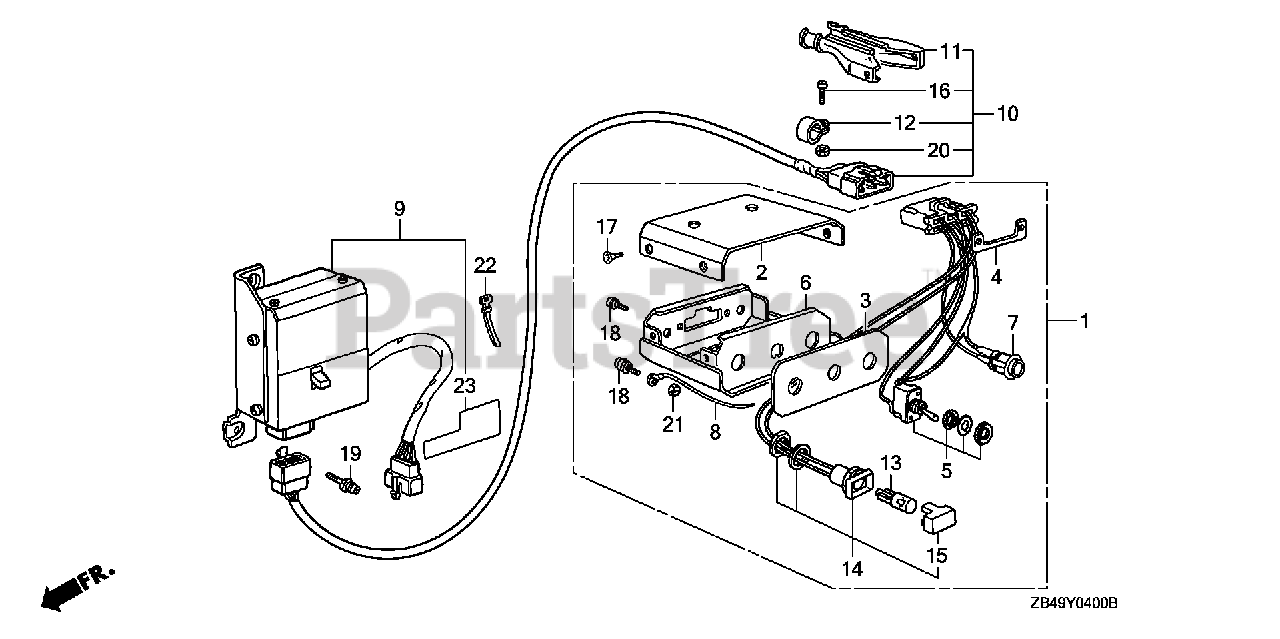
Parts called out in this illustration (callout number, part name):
1	BOX ASSY., SWITCH *R280* (POWER RED)
2	COVER (UPPER) *R8* (BRIGHT RED)
2	COVER (UPPER) *R280* (POWER RED)
3	PLATE, SWITCH & INDICATOR
4	PLATE, CONNECTOR SETTING
5	SWITCH, TOGGLE
6	CASE, SWITCH *R8* (BRIGHT RED)
6	CASE, SWITCH *R280* (POWER RED)
7	SWITCH, PUSH
8	WIRE, GROUND
9	BOX ASSY., RELAY
10	CABLE, REMOTE CONTROL (10M)
11	COVER, CONNECTOR
12	BAND
13	BULB, WEDGE BASE (12V/2W)
14	SOCKET ASSY., LAMP (GREEN)
15	LENS (GREEN)
16	SCREW, PAN (3X12)
17	SCREW, FLAT (4X8)
18	SCREW-WASHER (4X12)
19	SCREW-WASHER (6X25)
20	NUT, HEX. (3MM)
21	NUT, HEX. (4MM)
22	BAND B1, WIRE
23	MARK, REMOTE CONTROL
